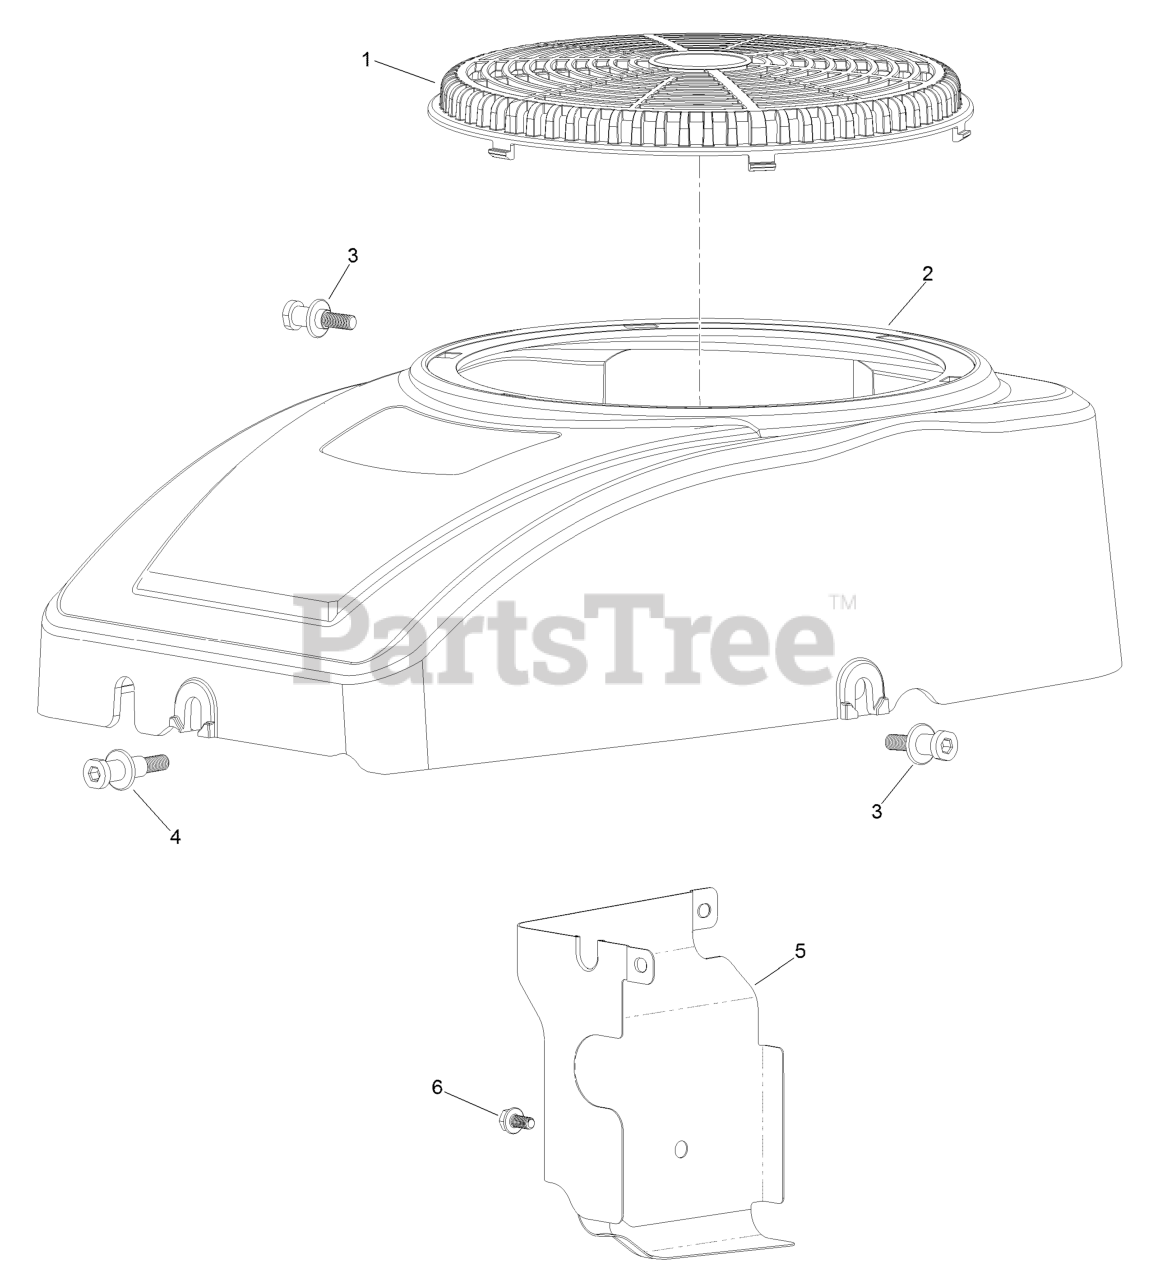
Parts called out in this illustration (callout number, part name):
1	SCREEN-STATIONARY
2	SHROUD-FAN
3	SCREW-SHOULDER, HH
4	SCREW-SHOULDER, HH
6	SCREW-HHF
